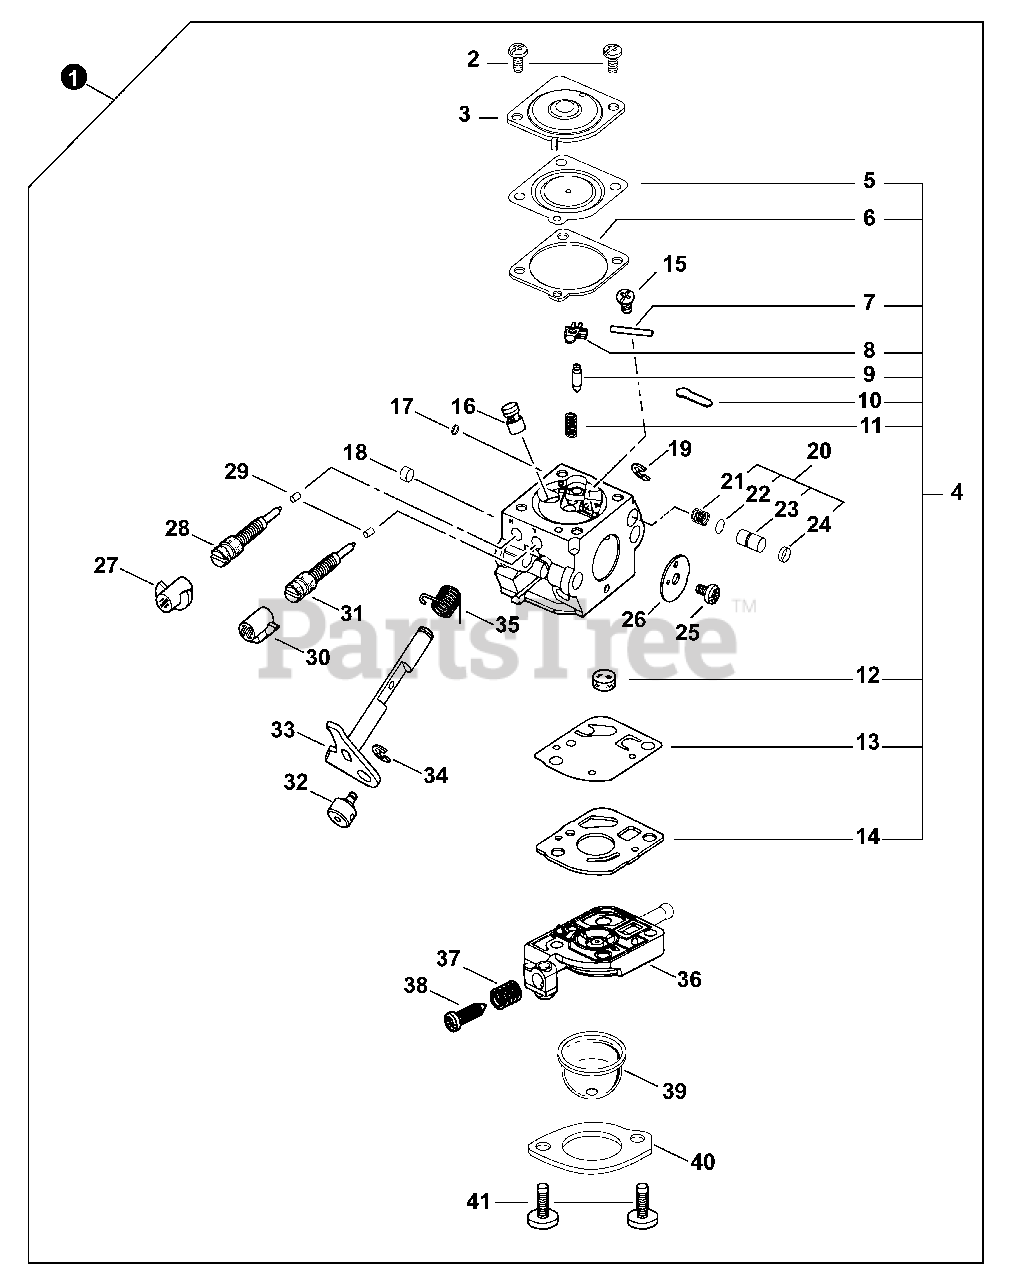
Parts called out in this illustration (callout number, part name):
1	CARBURETOR - C1U-K55
3	COVER, METERING DIAPHRAGM
4	REPAIR KIT, CARBURETOR
5	DIAPHRAGM, METERING
6	GASKET, METERING DIAPHRAGM
7	PIN, METERING LEVER
8	LEVER, METERING
9	VALVE, INLET NEEDLE
10	PLUG, WELCH
11	SPRING, METERING LEVER
12	STRAINER
13	DIAPHRAGM, PUMP
14	GASKET, PUMP
16	NOZZLE, CHECK VALVE
17	PLUG, WELCH
18	PIECE, LEVER
20	PUMP KIT
21	SPRING
22	O-RING
23	PLUNGER
24	STRAINER
26	VALVE, THROTTLE
27	CAP, LIMITER - RED
28	NEEDLE, HIGH SPEED
29	RETAINER
30	CAP, LIMITER - WHITE
31	SCREW
33	SHAFT, THROTTLE
35	SPRING, THROTTLE RETURN
36	BODY ASSY, PURGE
38	SCREW, THROTTLE ADJUST
39	BULB, PURGE
40	RETAINER
